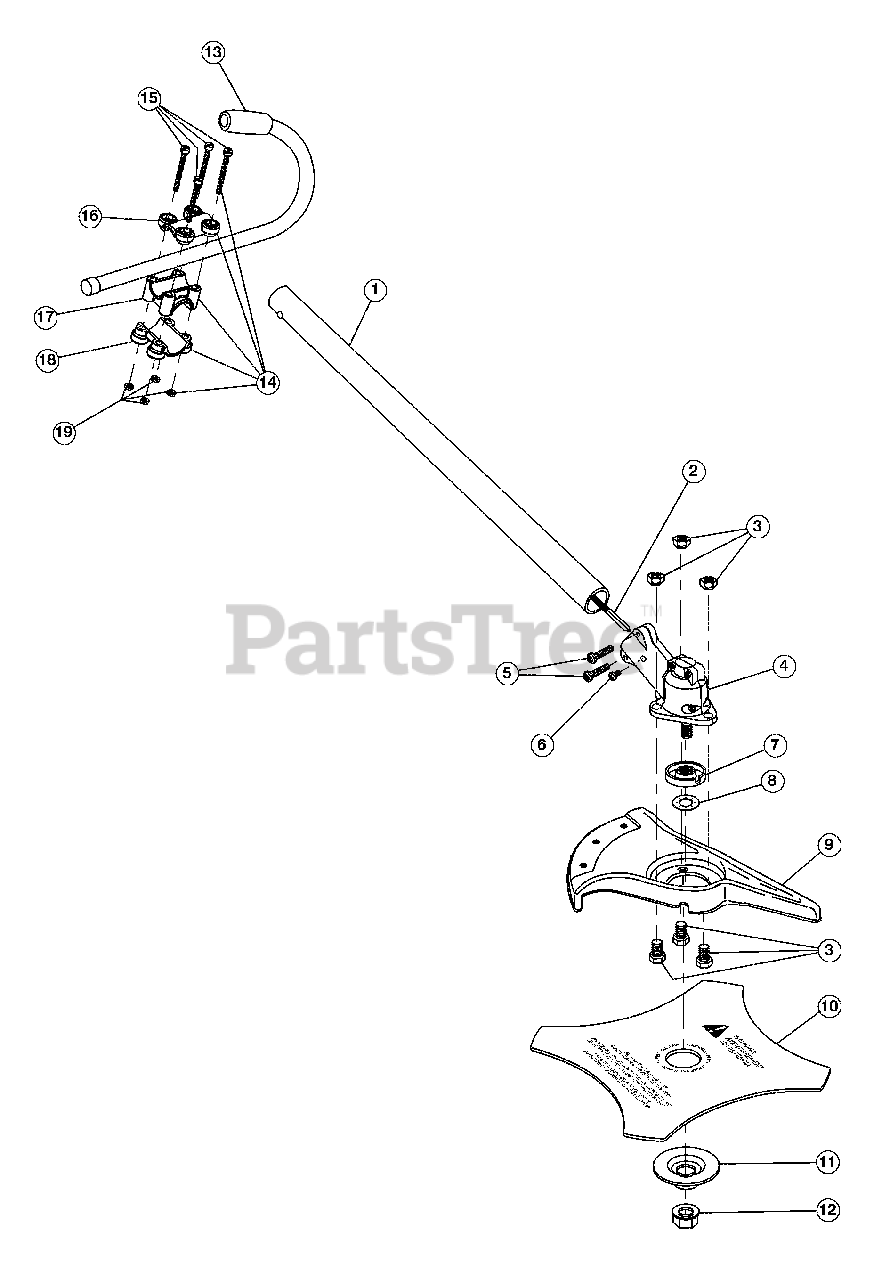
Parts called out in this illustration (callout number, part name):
1	Lower Drive Shaft Housing Assembly
2	Lower Flexible Drive Shaft
3	Shield Mount Screw Assembly
4	2 piece Gearbox Assembly (Incl. 5-6)
5	Gearbox Mounting Hardware
6	Anti-Rotation Screw
7	Blade Driver
8	Palnut
9	Blade Shield/Shield Mount
10	4-Tooth Blade
11	Retaining Washer
13	J-Handle Assembly
14	Handle Bracket Assembly (Incl. 15-19)
16	Upper Handle Clamp
17	Middle Handle Clamp
18	Lower Handle Clamp
